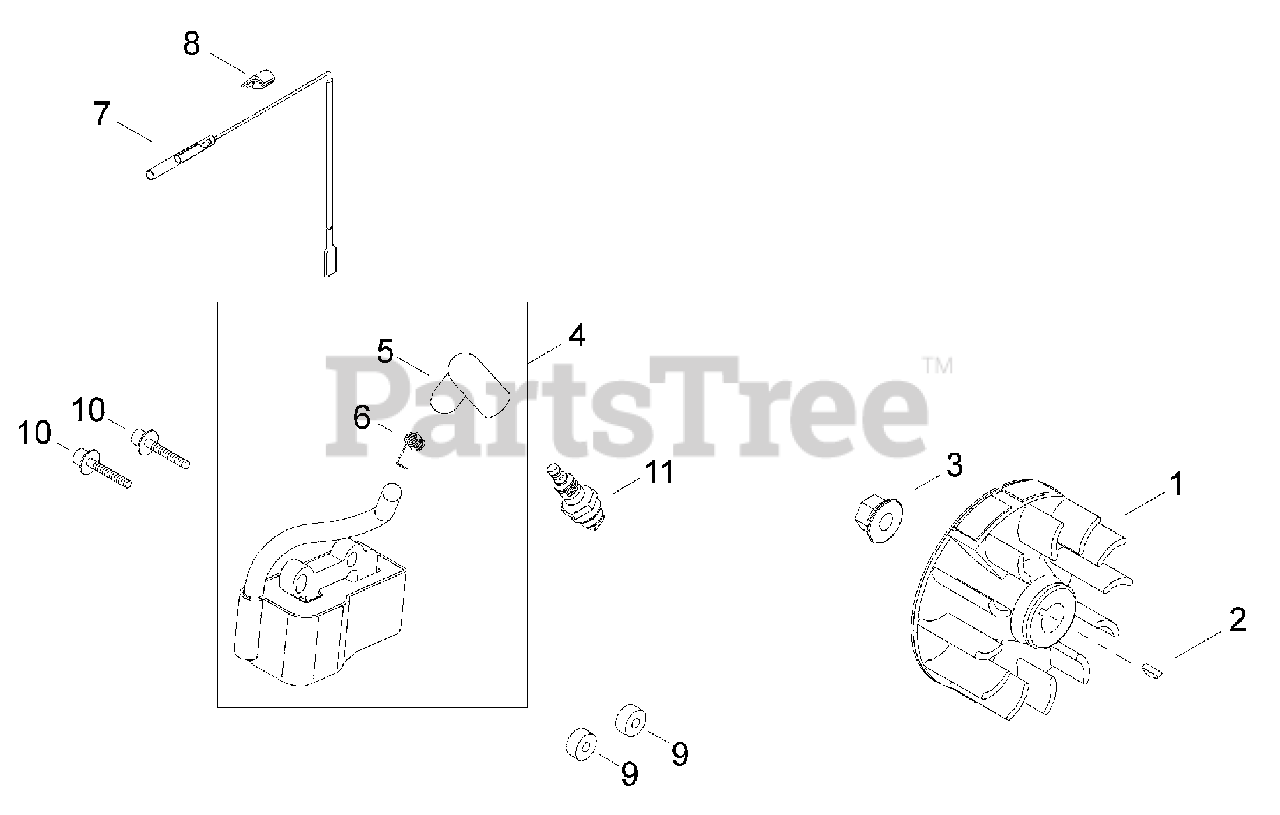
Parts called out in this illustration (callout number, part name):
1	FLYWHEEL
2	KEY, WOODRUFF 3×10
3	NUT M8
4	COIL ASSY, IGNITION
5	CAP, SPARK PLUG
6	TERMINAL, SPARK PLUG
7	LEAD - IGNITION
8	GROMMET, LEAD
9	INSULATOR 4.2×11×6
10	BOLT M4×26
11	SPARK PLUG - CMR5H
